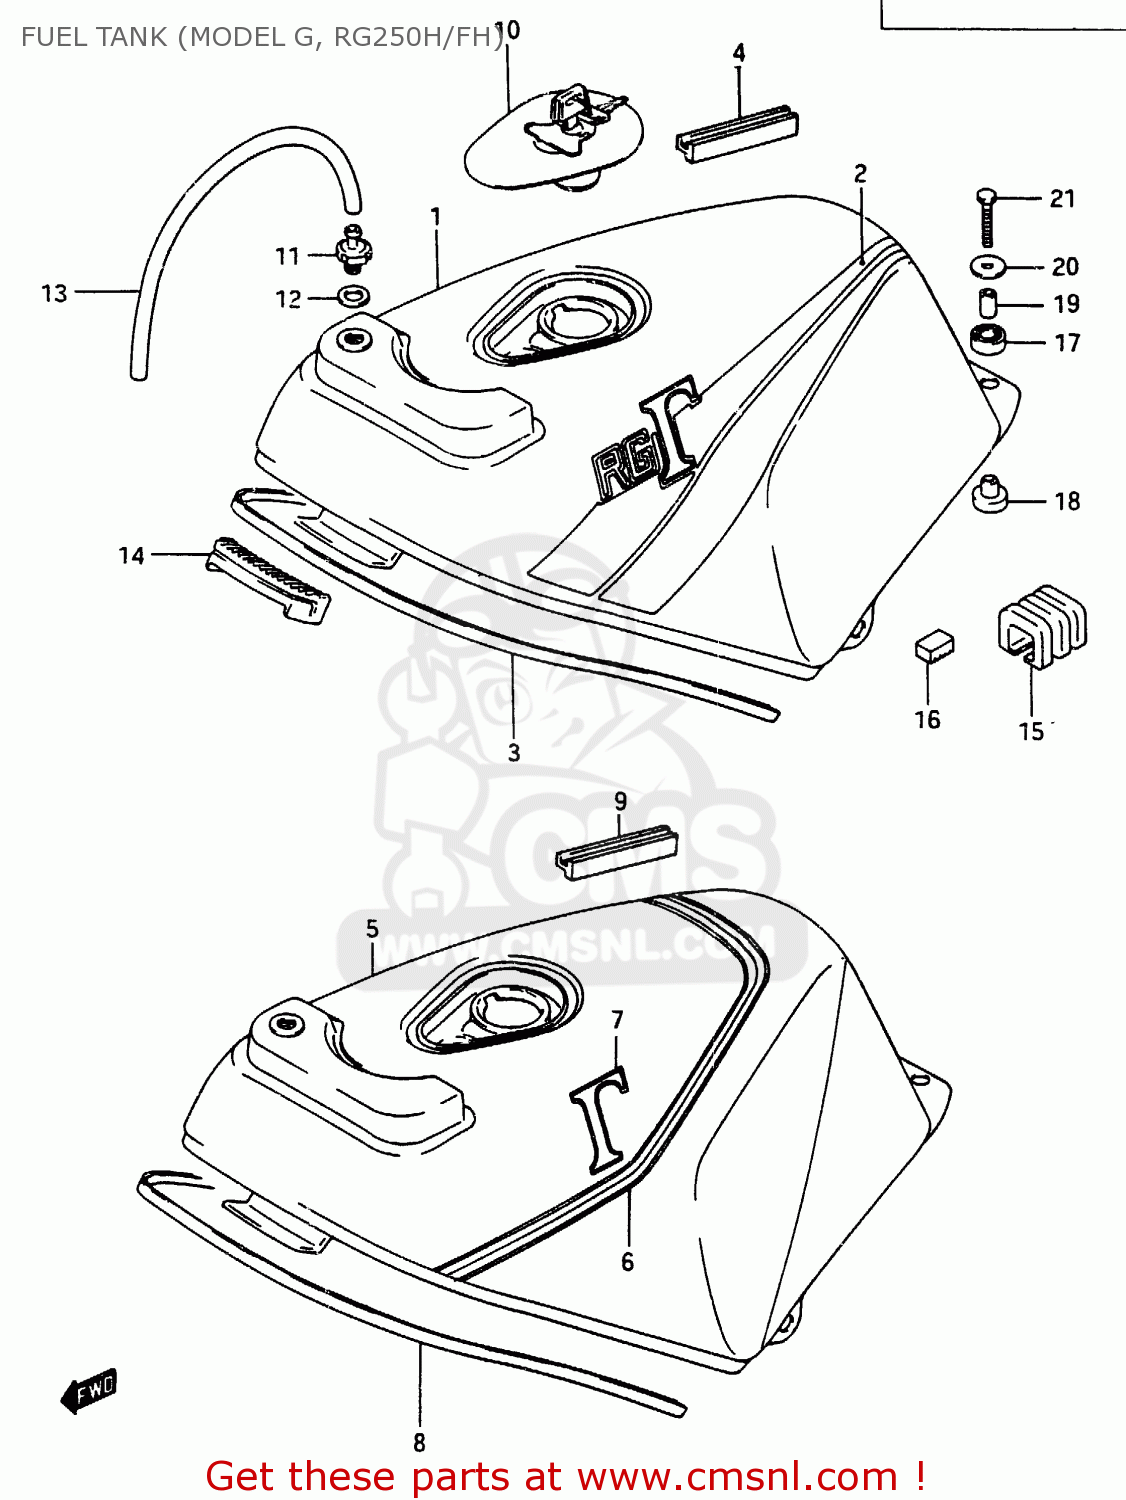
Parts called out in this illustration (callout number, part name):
1	TANK ASSY, FUEL
2	TAPE SET, FUEL TANK
3	MOLDING, FUEL TANK
4	MOLDING,FUEL TANK
5	TANK SET, FUEL
6	TAPE SET, FUEL TANK
7	EMBLEM
8	MOLDING, FUEL TANK
9	MOLDING,FUEL TANK
10	CAP ASSY, FUEL TANK
11	PLUG, FUEL TANK BREATHER
12	GASKET(12.5X20X2.5) (NAS)
13	HOSE
14	CUSHION,FUEL TANK FR
15	CUSHION, FUEL TANK CENTER
16	CUSHION,FUEL TANK SIDE
17	CUSHION
18	CUSHION
19	SPACER
20	WASHER (6.5X24X1.6)
21	BOLT ,6X35
